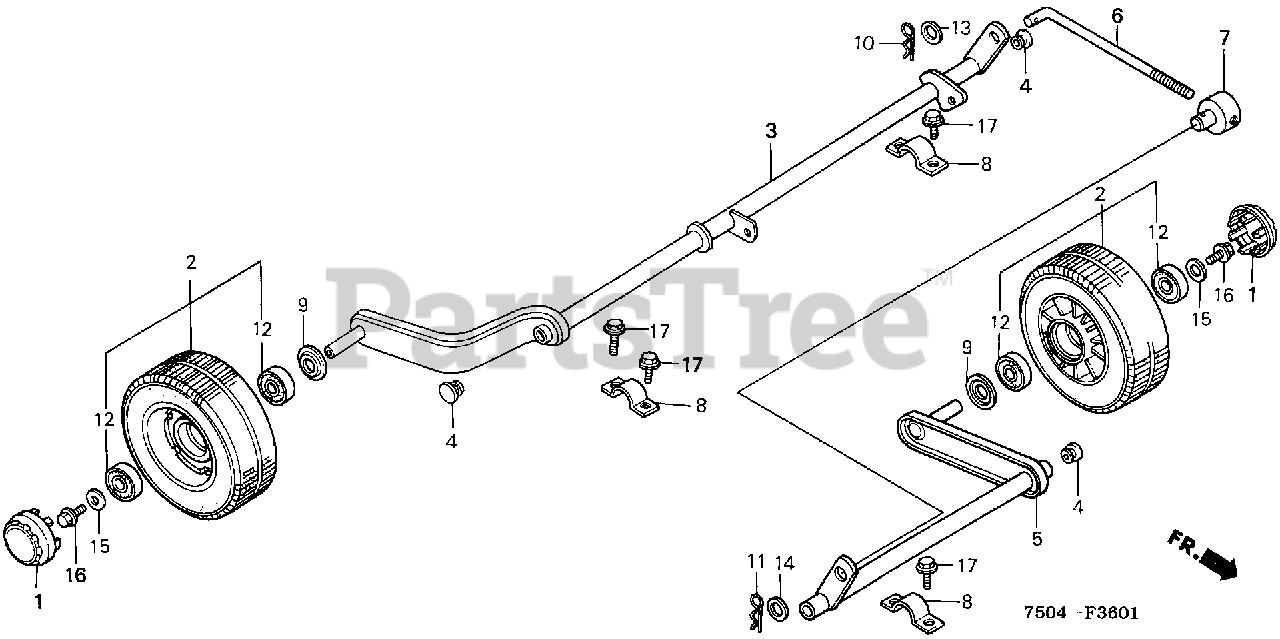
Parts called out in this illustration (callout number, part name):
1	CAP, WHEEL
2	WHEEL (6-2.0)
4	CAP, WHEEL SHAFT
5	SHAFT, L. WHEEL
6	BAR, ADJUSTING
7	PIN, ADJUSTING (NOT AVAILABLE)
8	BRACKET, R. SHAFT
9	WASHER, SPECIAL (12MM)
10	PIN, LOCK (2.3MM)
11	PIN, LOCK (2.3MM)
12	BEARING, RADIAL BALL
13	WASHER, FLAT (12MM)
14	WASHER, PLAIN (14MM)
15	WASHER, PLAIN (6MM)
16	BOLT, FLANGE (6X12)
17	BOLT, FLANGE (8X14)
